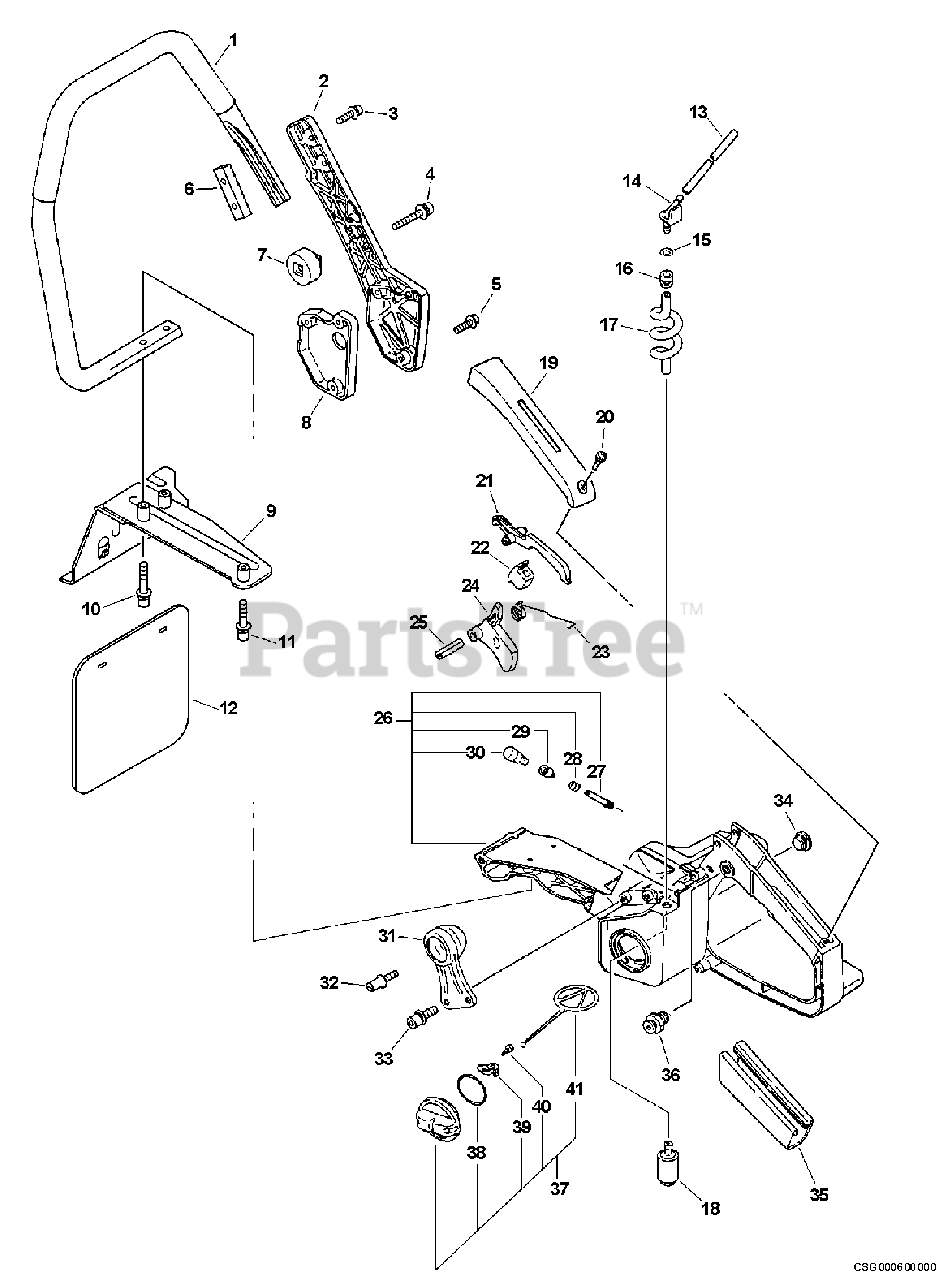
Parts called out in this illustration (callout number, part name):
1	HANDLE - FRONT
2	BRACKET, HANDLE
3	SCREW - 5X20
4	SCREW - 5X30
5	SCREW - 5X35
8	SPACER
9	BRACKET, HANDLE
10	SCREW - 5X35
11	SCREW - 5X30
12	SHIELD
13	PIPE - 3X6X100 -- BLACK
14	CONNECTOR, PIPE
15	CLIP - 6.5
16	GROMMET
17	PIPE - BLACK
18	FILTER, FUEL
19	COVER, HANDLE
20	SCREW - 4X14
21	LEVER, TRIGGER LOCKOUT
23	SPRING, TRIGGER
24	TRIGGER, THROTTLE
25	PIN - SPRING -- 5X25
26	HANDLE - REAR
27	PIPE - VENT
28	CLIP - 5.5
29	COVER, VENT
30	VENT, FUEL TANK
33	SCREW - 5X14
35	GRIP, HANDLE
36	LATCH, THROTTLE
37	CAP ASSY
38	O-RING - 29
39	RETAINER
40	SCREW - 3X8
41	CONNECTOR, CAP
